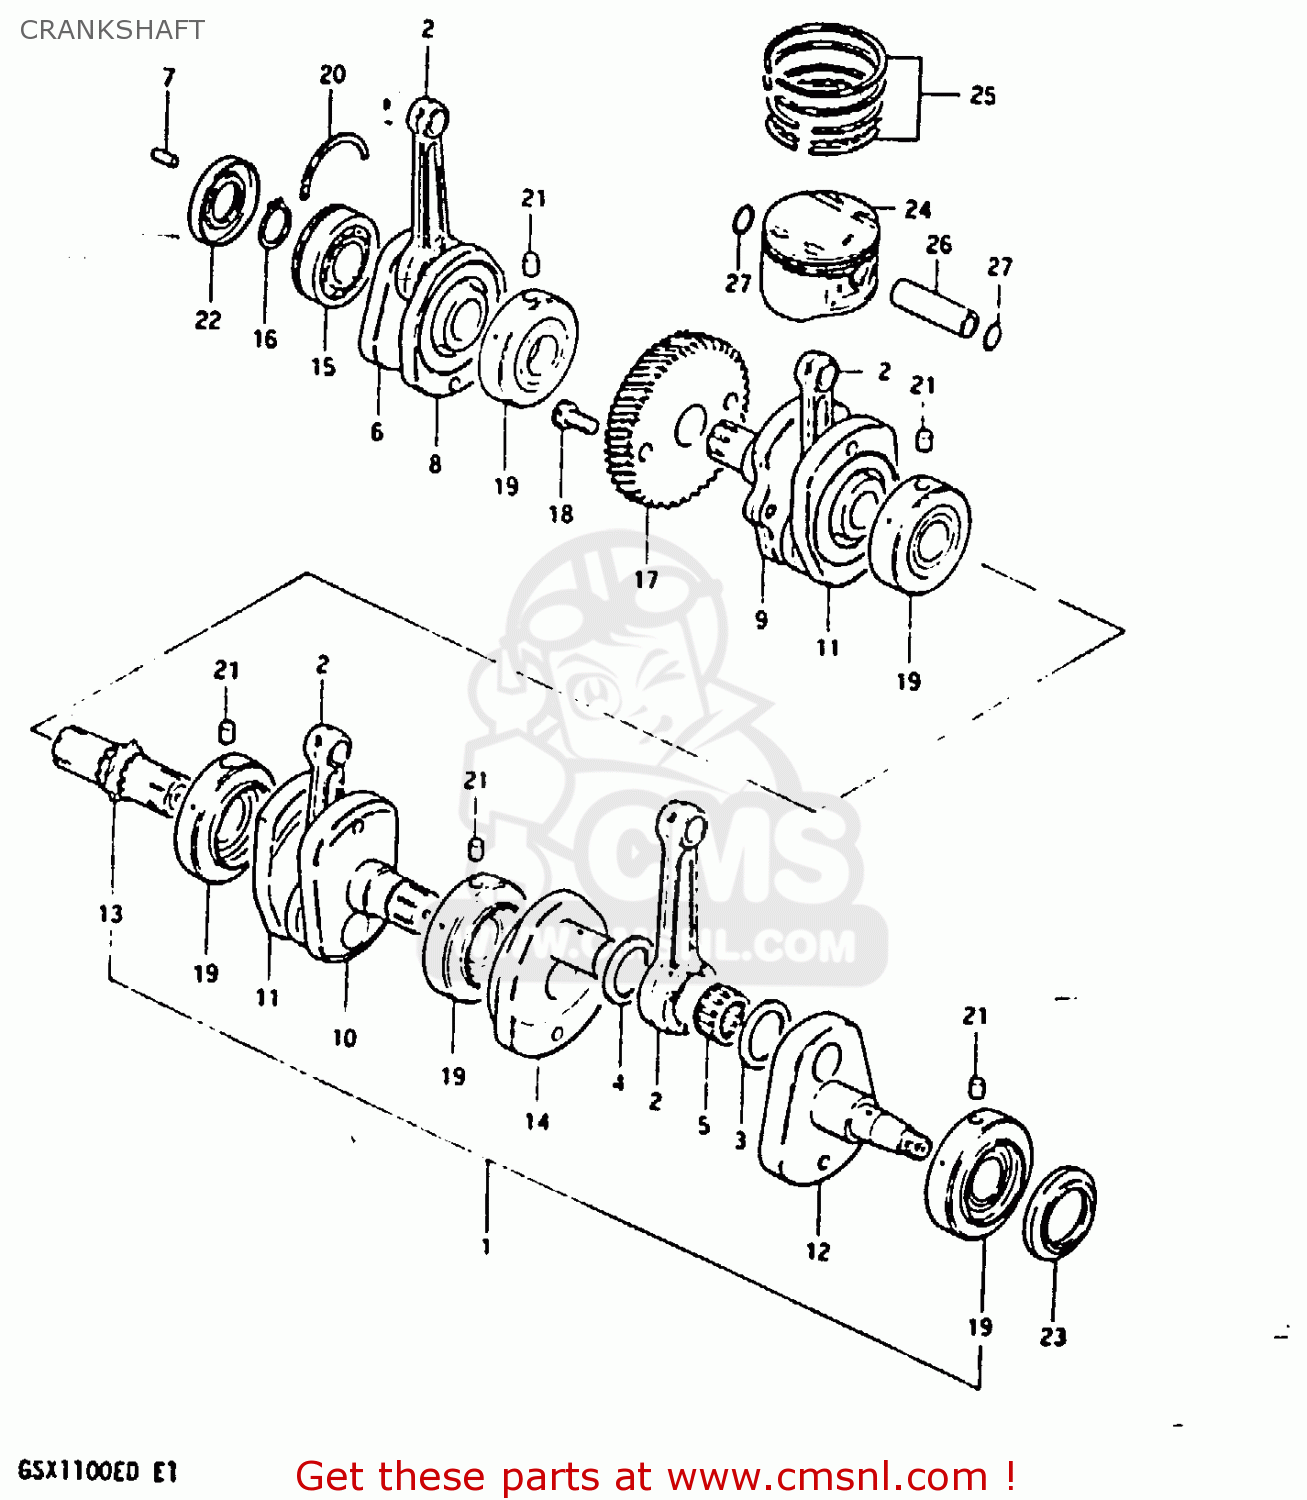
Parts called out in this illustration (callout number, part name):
1	CRANKSHAFT ASSEMBLY
2	CONNECTING ROD
3	WASHER(31X48.5X1)
4	WASHER(31X48.5X2)
5	BEARING(31X39X21)
6	CRANKSHAFT,RIGHT
7	PIN
8	WEB,CRANK
9	CRANKSHAFT
10	CRANKSHAFT,MIDDLE,LEFT
11	WEB,CRANK,MIDDLE
12	CRANKSHAFT,LH
13	SHAFT,TIMING CHAIN DRIVE
14	WEB,CRANK,LEFT
15	BEARING(30X72X19)
16	CIRCLIP,30MM
17	GEAR,PRIMARY DRIVE
18	BOLT
19	BEARING
20	C RING
21	PIN
22	SEAL,OIL(30X72X11)
23	SEAL,OIL(47.3X60X6.5)
24	PISTON
25	RING SET,PISTON
26	PIN,PISTON
27	CIRCLIP,PISTON PIN
